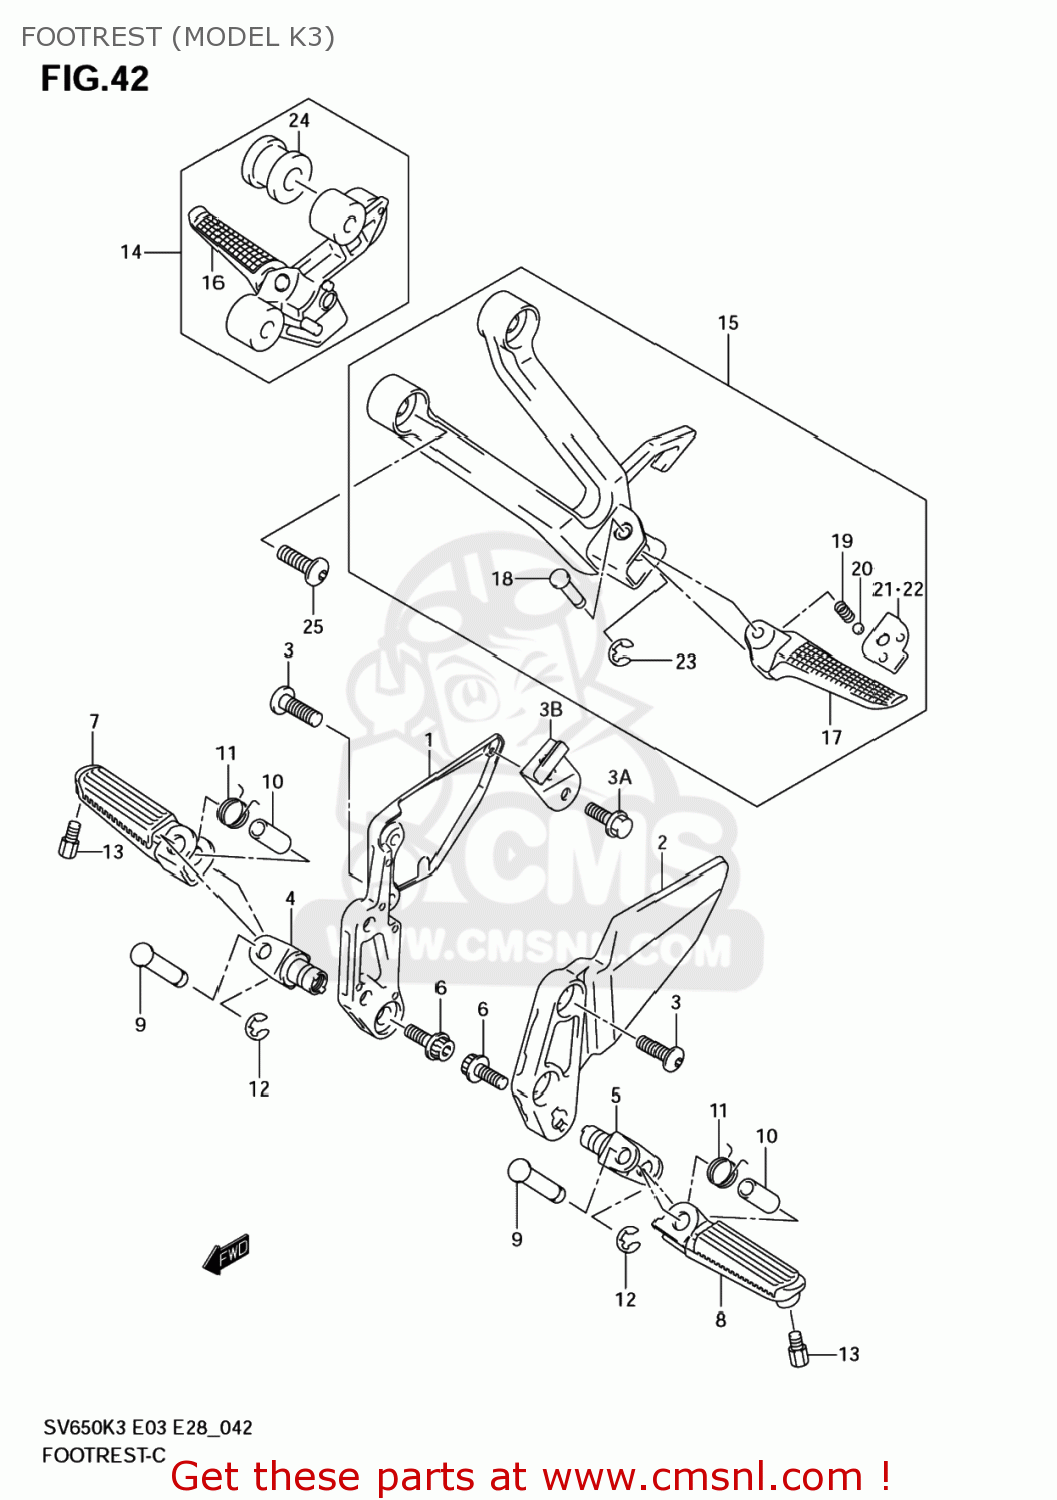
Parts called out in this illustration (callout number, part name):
1	BRACKET,FR FOOTREST,R
2	BRACKET,FR FOOTREST,L
3	BOLT(8X20)
3A	BOLT
3B	REINF,FOOTREST BRACKET
4	HOLDER,FOOTREST,R
5	HOLDER,FOOTREST,L
6	BOLT(10X28)
7	BAR,FR FOOTREST,R
8	BAR,FR FOOTREST,L
9	PIN
10	SPACER(8.1X12X22)
11	SPRING
12	E.RING
13	BOLT,BANK SENSOR
14	FOOTREST ASSY,PILLION,R
15	FOOTREST ASSY,PILLION,L
16	BAR,PILLION FOOTREST,R
17	BAR,PILLION FOOTREST,L
18	PIN
19	SPRING
20	BALL
21	PLATE,PILLION FOOT,R
22	PLATE,PILLION FOOT,L
23	E-RING
24	BUSH
25	BOLT(8X23)
